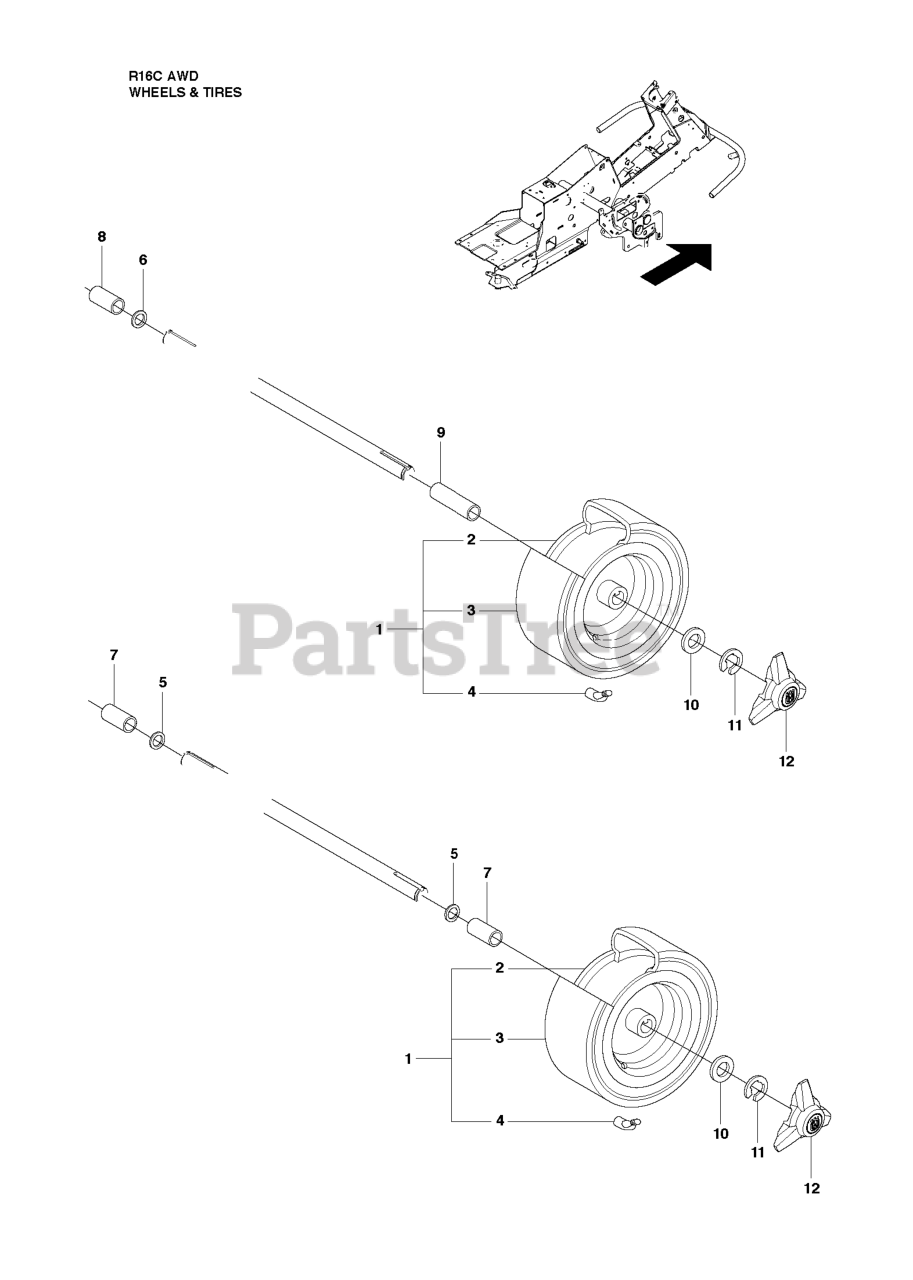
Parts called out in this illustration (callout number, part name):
3	TIRE
4	VALVE
7	SPACE SLEEVE
11	RETAINING RING
